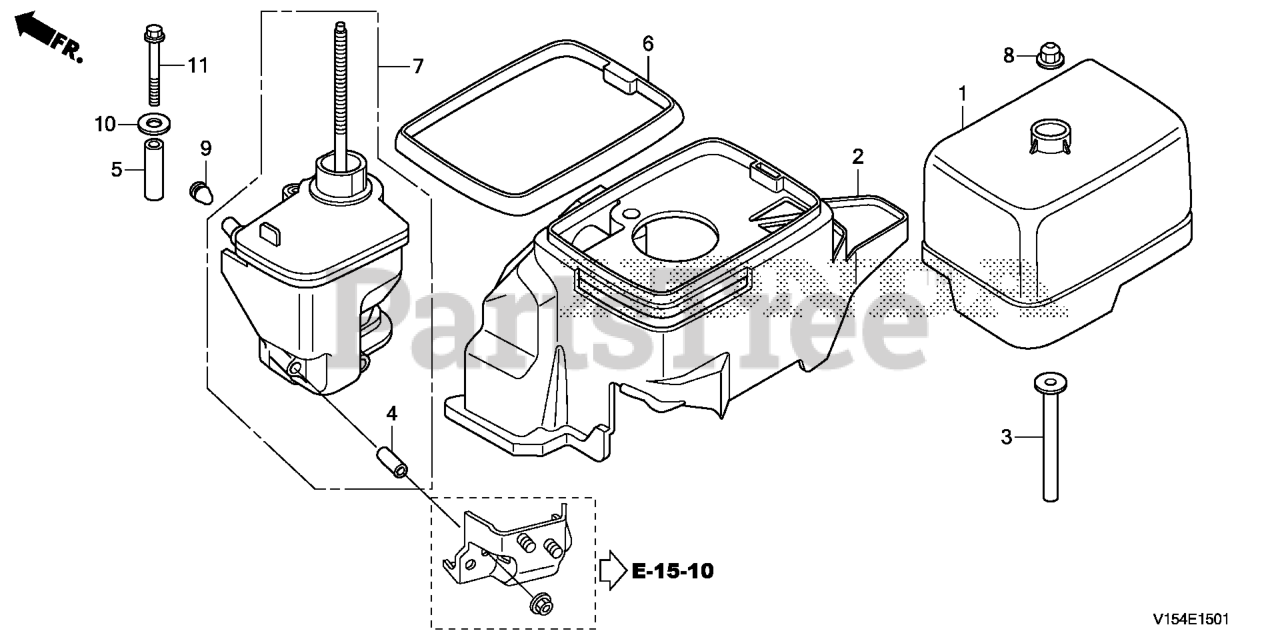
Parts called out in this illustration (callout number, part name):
1	COVER, AIR CLEANER HOUSING
2	NOSE, MUFFLER
3	COLLAR A, AIR CLEANER
4	COLLAR, AIR CLEANER
5	COLLAR B, AIR CLEANER
6	SEAL, AIR CLEANER
7	ELBOW, AIR CLEANER
8	NUT, FLANGE (6MM)
9	PLUG, CONE TYPE
10	WASHER, PLAIN (6MM)
11	BOLT, FLANGE (6X55)
